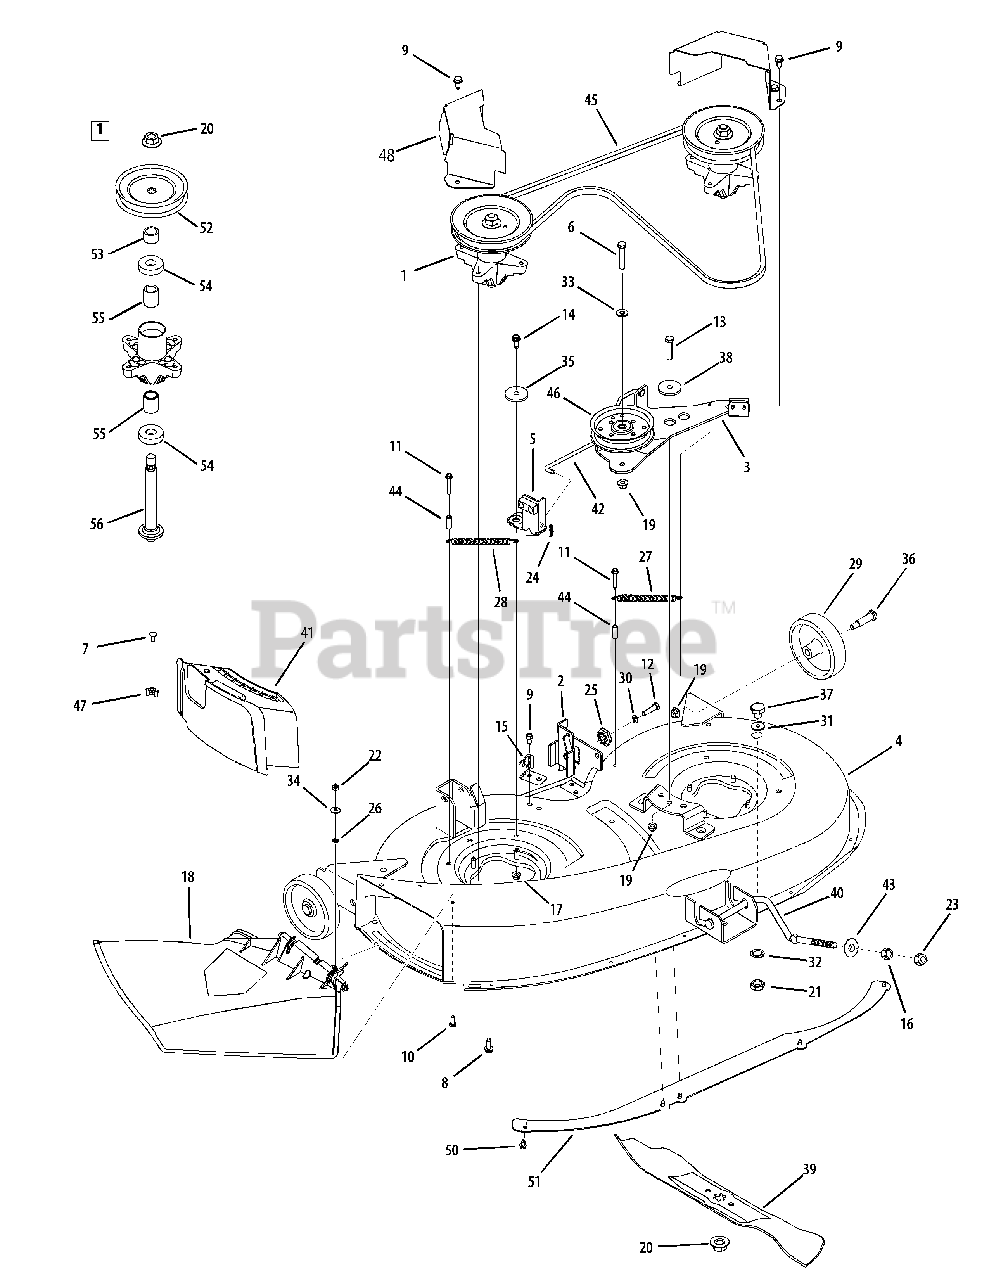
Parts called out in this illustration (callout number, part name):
1	Pulley Spindle Ass’y 5.75 dia.
2	Deck Hanger Brkt. Ass'y
3	Deck Brake Assembly
4	Deck Shell, 38" (w/o wheel brackets)
5	Deck Brake Assembly
6	Hex Screw 3/8-16 x 1.75
7	Carriage Bolt 1/4-20 x .62
8	S-Tapp Scr 5/16-18 x .75
9	Hex Scr 5/16-18 x .625
10	Hex Bolt 1/4-20 x 1.00
11	Hex Wash HD Bolt 1/4-20 x 1.50" Lg.
12	Hex Wash Tap Scr 5/16-18 x 1.25
13	Hex Bolt 3/8-16 x 1.25
14	Hex Bolt 5/16-18 x .75" Lg. Gr. 5
15	Deck Engagement Cable Bracket
16	Hex Nut 1/2-13
17	Hex Flange Locknut 5/16-18 Gr. F, Nylon
18	Side Discharge Chute Assembly
19	Hex Flange Locknut 3/8-16 Gr. F Nylon
20	Hex Flange Locknut 5/8-18
21	Hex Nut M16-1.5 DIN 936
22	Hex Nut 1/4-20 Gr. 5
23	Hex Nut, 1/2-13
24	Int. Cotter Pin .072 x 1.13" Lg.
25	Deck Adjustment Gear
26	Bolt Retainer 1/4" x .50" OD
27	Extension Spring .75 dia. x 6.37 Lg.
28	Extension Spring .50 dia x 6.37
29	Wheel Ass’y - Deck 5" x 1.38"
30	L-Wash 5/16 ID
31	Flat Washer .640 ID x 1.24 OD x .06
32	L-Washer Internal
33	Flat Washer
34	Cupped Washer .265 ID x .75 OD x .062
35	Shoulder Spacer
36	Shoulder Bolt .498 Dia x 1.53 x 3/8-16
37	Screw Plug M16 x 1.50
38	Shoulder Spacer .8540 x .200
39	Blade 19.38" Lg.
40	Deck Rod, Front Adjustable
41	Mulching Plug
42	Brake Control Rod
43	Deck Lift Pivot Cup
44	Spacer .260 x .375 x 1.030 Lg.
46	Idler Pulley w/Flange 4.25 Dia
47	Wing Nut 1/4-20 Thd.
48	Belt Cover 5.66 dia.
50	Screw, 1/4-20 x .50
51	38" Deck Skirt
53	Spacer, .820 x 1.150 x .480
54	Ball Bearing .787 ID x 1.85 OD x .551
55	Spacer .80 x 1.10 x 1.322
56	Spindle Shaft 5.5
